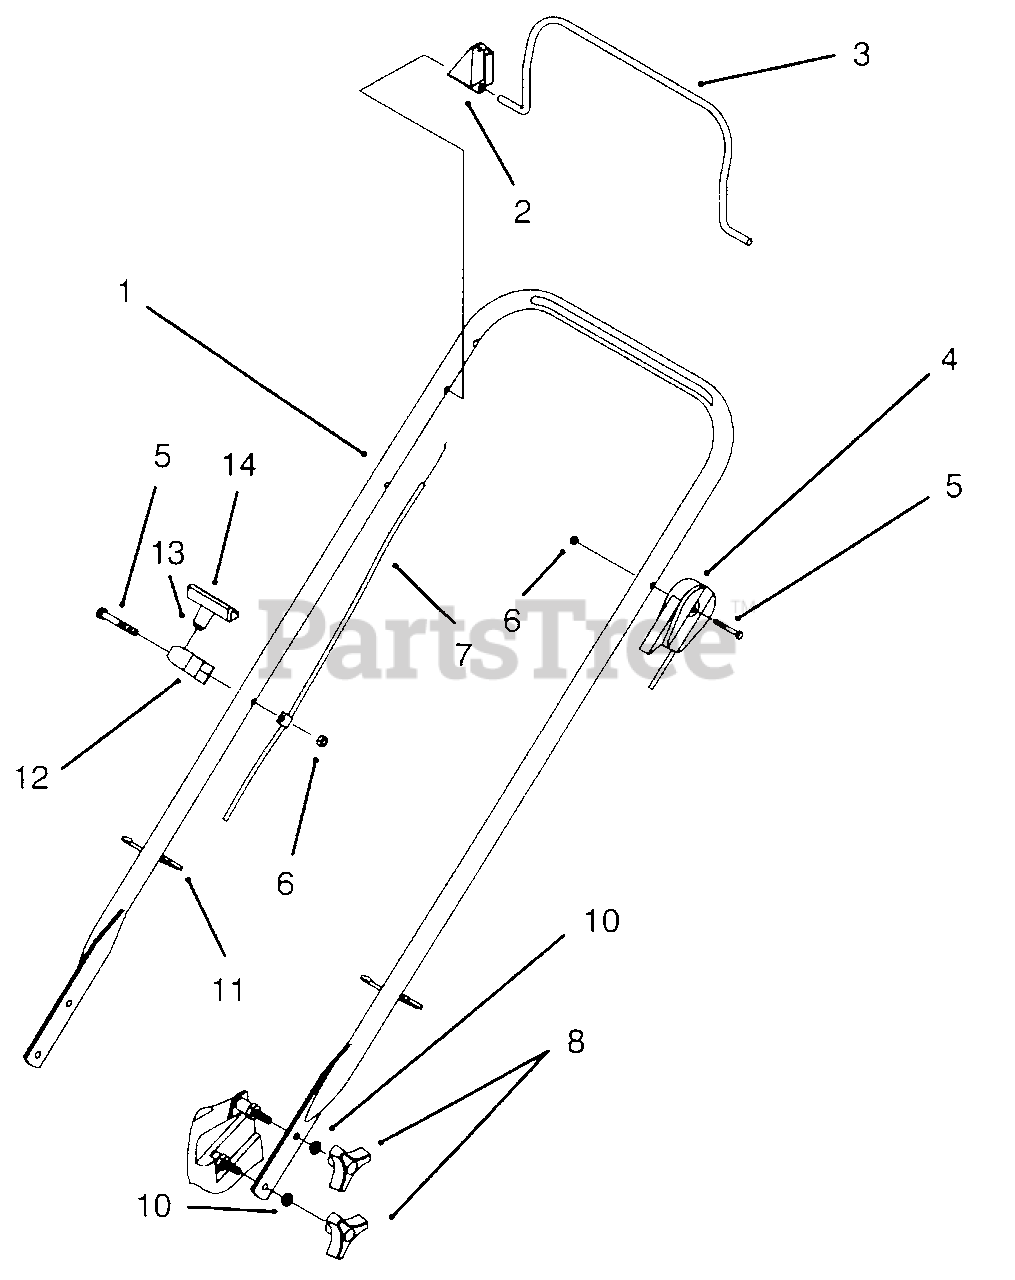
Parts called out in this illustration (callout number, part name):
2	Stop-Pivot
3	Bail-Flywheel Brake
4	Cable-Throttle
5	Screw-Hex Hd. Cap
6	Nut-Lock
7	Cable-Brake
8	Knob
10	Washer-Lock
11	Tie-Cable
12	Guide-Rope
13	Handle-Starter
14	Clip-Rope Insert
